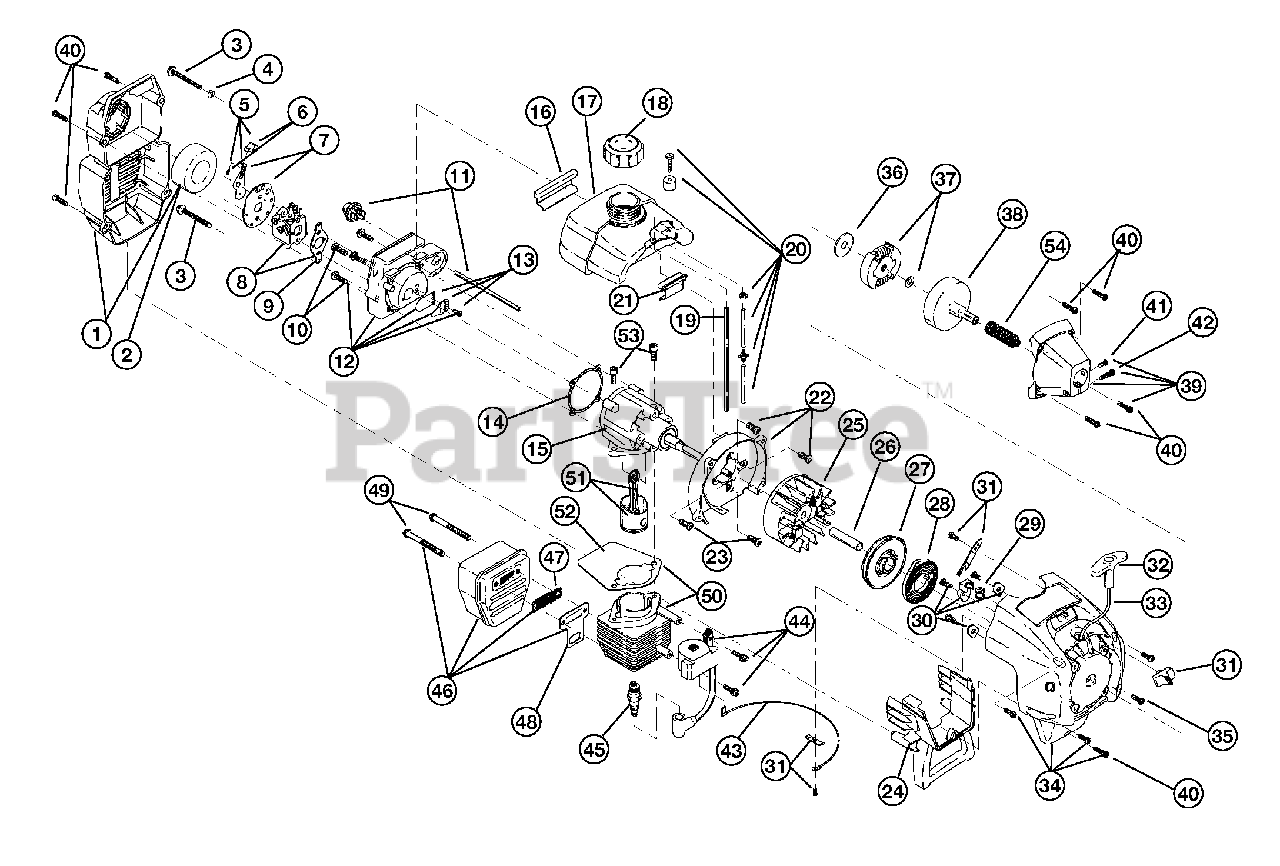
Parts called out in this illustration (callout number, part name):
1	Air Cleaner/Muffler Cover Assembly
2	Air Cleaner Filter
3	Carburetor Mounting Screw Assembly
4	Wavey Washer
5	Choke Lever Assembly
6	Choke Knob and Screw
7	Choke Lever and Plate
8	Carburetor Assembly
9	Carburetor Gasket
10	Carb Mount Screw
11	Primer and Hose Assembly
12	Carb Mount Assembly
13	Reed Assembly
14	Carburetor Mount Gasket
15	Crank Case Service Assembly
16	Rear Mounting Pad
17	Fuel Tank Assembly
18	Fuel Cap Assembly
19	Fuel Return Line
20	Fuel Line Assembly
21	Front Mounting Pad
22	Shroud Assembly
23	Shroud Screw
24	Shroud Extension and Stand
25	Flywheel Assembly
27	Recoil Pulley Assembly
28	Recoil Spring
29	Rope Guide
30	Pulley Retainer Assembly
31	Switch Assembly
32	Pull Handle
34	Starter Housing Assembly
35	Housing Screw
36	Clutch Washer
37	Clutch Rotor Assembly
38	Clutch Drum Assembly
39	Clutch Cover Assembly
40	Cover Screw
41	Anti-Rotation Screw
42	Clamping Screw
43	Wire Lead
44	Module Assembly
45	Spark Plug
46	Muffler Assembly
47	Spark Arrestor Screen
48	Exhaust Gasket
49	Muffler Mounting Bolt
50	Cylinder Assembly
51	Piston and Rod Assembly
52	Cylinder Gasket
53	Cylinder Bolt
